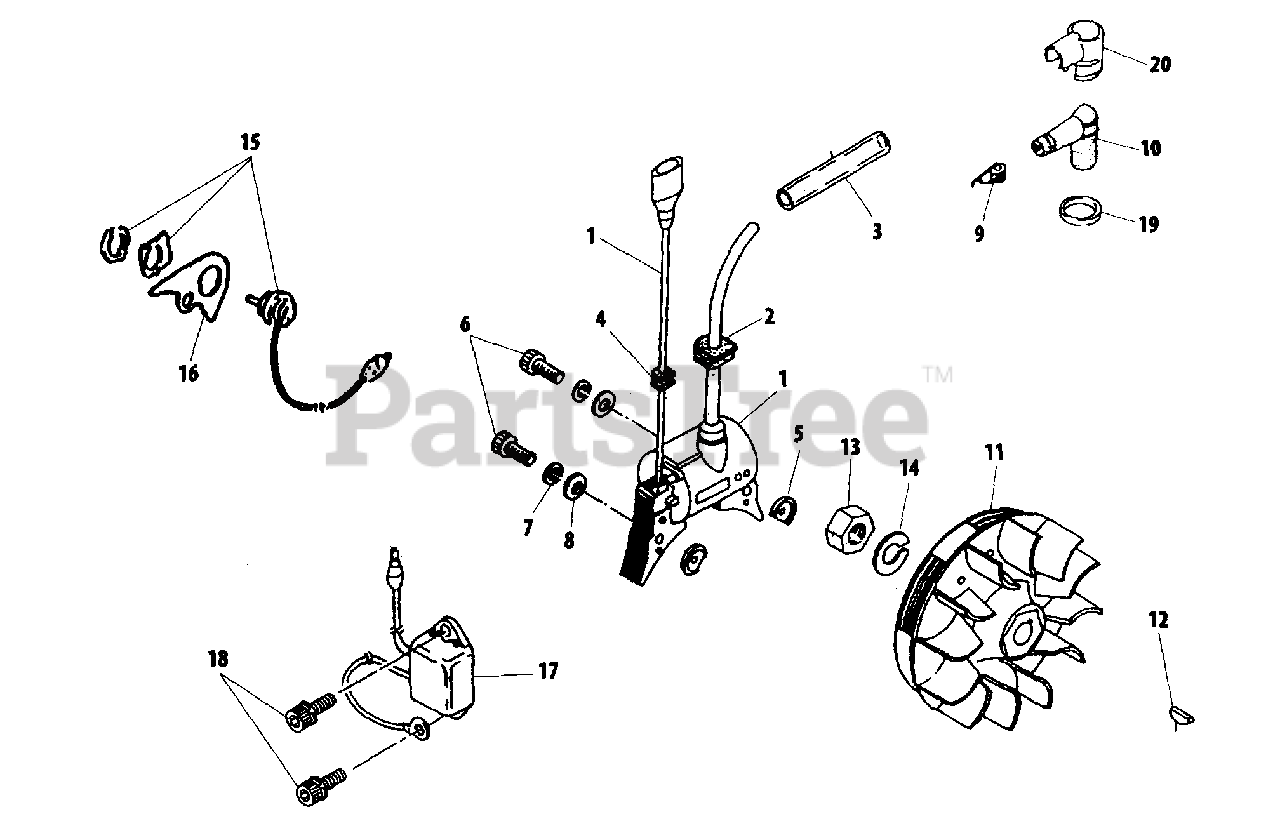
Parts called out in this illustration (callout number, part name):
1	COIL, IGNITION
2	GROMMET
3	TUBE, INSULATOR
4	GROMMET, LEAD
5	COLLAR 4
6	BOLT
7	WASHER, SPRING 4 MM
8	WASHER 4.3×9.6×0.8
9	TERMINAL, SPARK PLUG
10	CAP, SPARK PLUG
11	FLYWHEEL
12	KEY, WOODRUFF 3×10
13	NUT 10×1.25
14	WASHER, SPRING 10
15	SWITCH, ON-OFF
16	BRACKET
17	ELECTRONIC UNIT
18	BOLT M4×12
19	SEAL, SPARK PLUG
20	COVER, CAP
